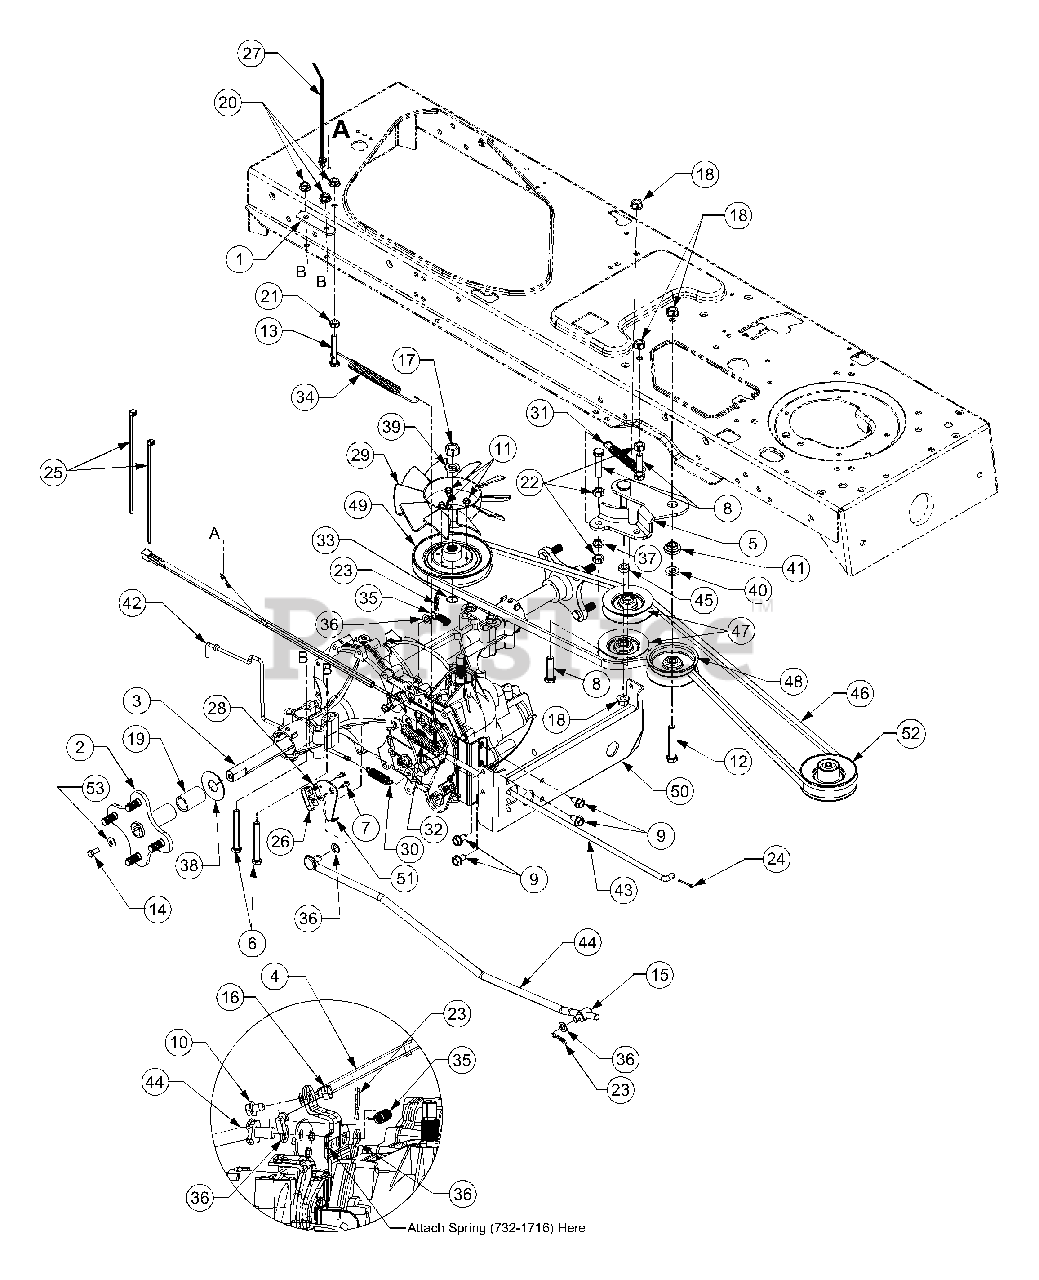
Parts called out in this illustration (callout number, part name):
2	Hub Assembly, Wheel (Double "D")
3	Transmission, Hydrostatic Uses Double "D" axle
4	Harness Assembly, Ground & Reverse
6	Hex Cap Screw, 5/16-18,3.5, Gr5
7	Screw, #8-18, 0.500
8	Hex Cap Screw, 3/8-16, 1.50, Gr5
9	Screw, 5/16-12, 0.75
10	Screw, 1/4-20, 0.5
11	Screw, #12-24, 0.375
12	Hex Cap Screw, 3/8-16, 2.25, Gr5
13	Hex Cap Screw, 5/16-18, 2.00, Gr5
14	Hex Cap Screw, 5/16-24 x .750
15	Ferrule, 3/8-24 x .375 Dia
16	Nut, Hex Lock, 1/4-20
17	Nut, Hex, 1/2-20, Gr2
18	Nut, Nylon Lock, 3/8-16
19	Sleeve, 1.5"
20	Nut, Nylon Lock, 5/16-18, Gr5
21	Nut, Hex, 5/16-18, Gr5
22	Nut, Hex, 3/8-16, Gr8
23	Pin, Cotter, .072 Dia. x 1.13 Lg
24	Pin, Cotter, 3/32, 1.0
25	Cable, Tie, 3/16 x .05 x 7.4
26	Switch, Spring, Short
27	Tie, Cable, Push Mount 7.5 Lg
28	Plate, Insulator Nut
29	Fan, Blade, 10"
30	Spring, .48 OD x 2.03 Extension
31	Spring, Extension, .50 Dia x 3.97 Lg
32	Spring, Extension, .59 OD x 4.00 Lg
33	Ring, Wire
34	Spring, Extension, .500 Dia x 7.0 Lg
35	Spring, Extension, 3/8 OD x 1.44 Lg
36	Washer, Flat, .385 x .62 x .063
37	Washer, Lock, 3/8 , Regular Duty
38	Washer, Flat, .755 x 1.92 x .060
39	Washer, Lock, 1/2 , Regular Duty
40	Washer, Flat, .407 x .812 x .135 Hdn
41	Spacer, Shoulder, 1.00 x .38 x .38
42	Rod, Hydro Bypass
43	Rod, Brake, Hydro
44	Rod, Control, Hydro
45	Spacer, .376 ID x .625 OD x .22
46	Belt, V Type, Poly, Ax79.2 Lg.
47	Pulley, Idler, V Type x 3.06 Dia
48	Pulley, Idler, Flat 2.75 OD
49	Pulley, Input, 5.0 Dia., S/N A174H20368 & before
52	Pulley, Engine, 3.56 Dia.
53	Belle Washer
